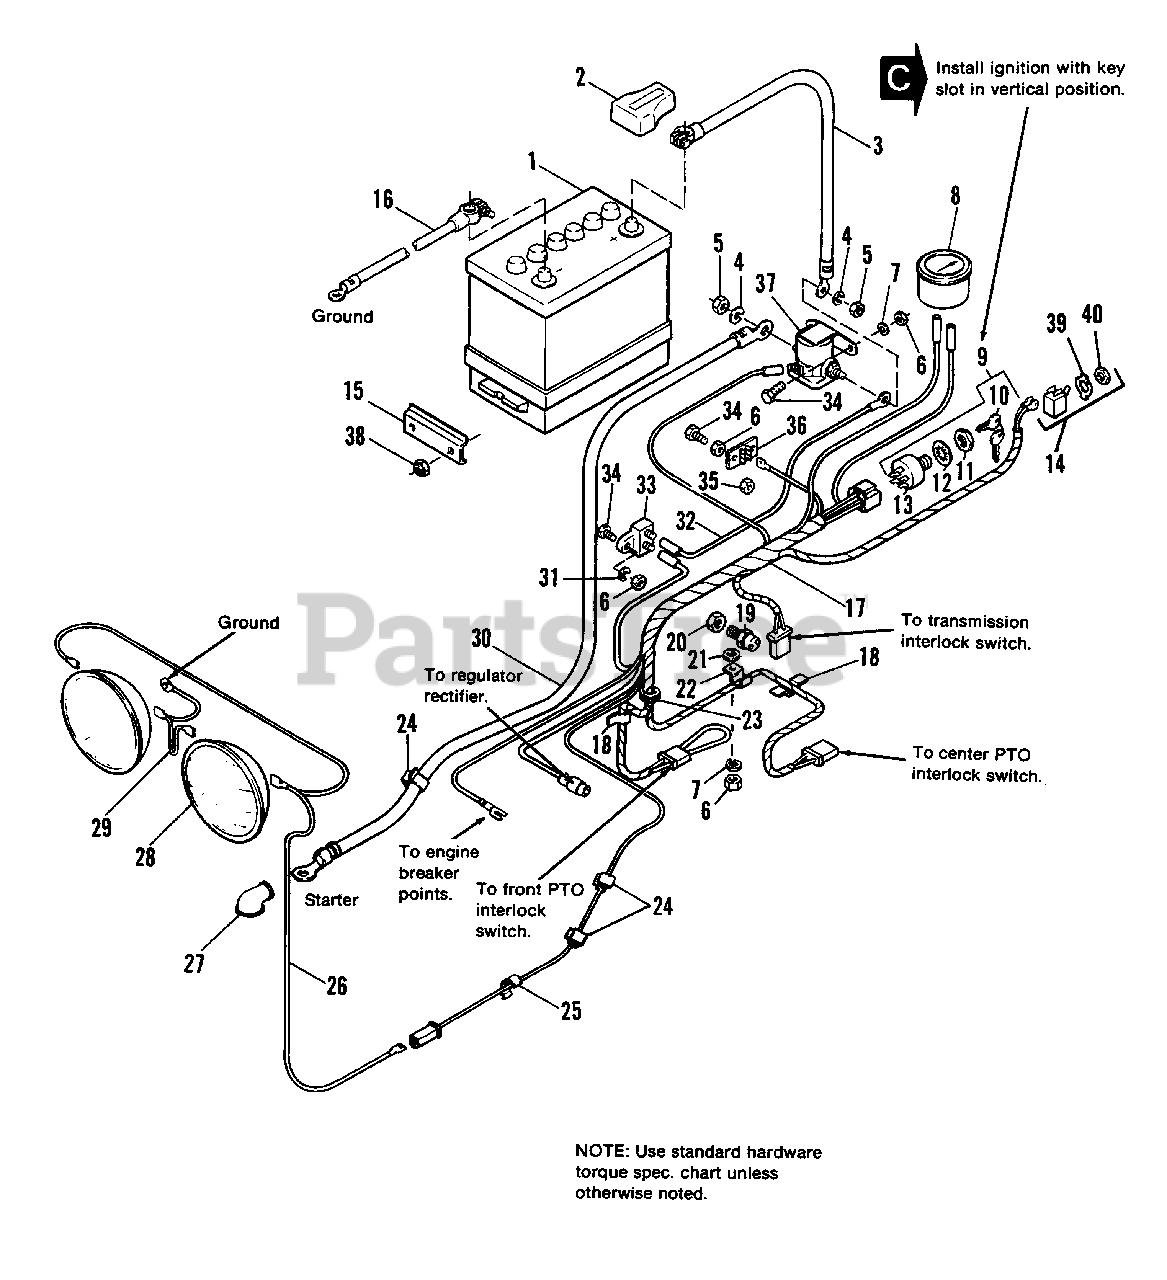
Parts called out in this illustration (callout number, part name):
1	BATTERY (Includes decal)
2	PROTECTOR, Terminal
3	CABLE (Battery to Solenoid)
4	LOCKWASHER, 5/16
5	NUT, Hex, Full, 5/16-18
6	NUT, Hex, Full, 1/4-20
7	LOCKWASHER, 1/4
9	SWITCH & KEY ASSY., lgnition
10	KEY SET (2)
11	NUT, Special
12	LOCKWASHER, Int., 5/8
14	SWITCH, Toggle
16	CABLE (Battery to Ground)
17	HARNESS ASSY.
18	CLIP, Wire
19	SWITCH, Interlock
20	NUT, Pal
21	WASHER, Plain
22	CLIP, Cable
24	CLIP, Tinnerman
25	CLIP, Tinnerman
27	COVER, Terminal
28	LAMP, Sealed Beam, G.E. #4411-1
29	WIRE ASSY.
30	CABLE (Solenoid to Starter)
31	LOCKWASHER, Ext., 1/4
33	BREAKER, Circuit
34	CAPSCREW, Hex Hd., 1/4-20 x 5/8
35	LOCKNUT, Hex, 1/4-20
36	BOARD, Terminal
37	SOLENOID, Starter
38	LOCKNUT, Hex, Esna, 5/16-18
40	NUT, Switch
